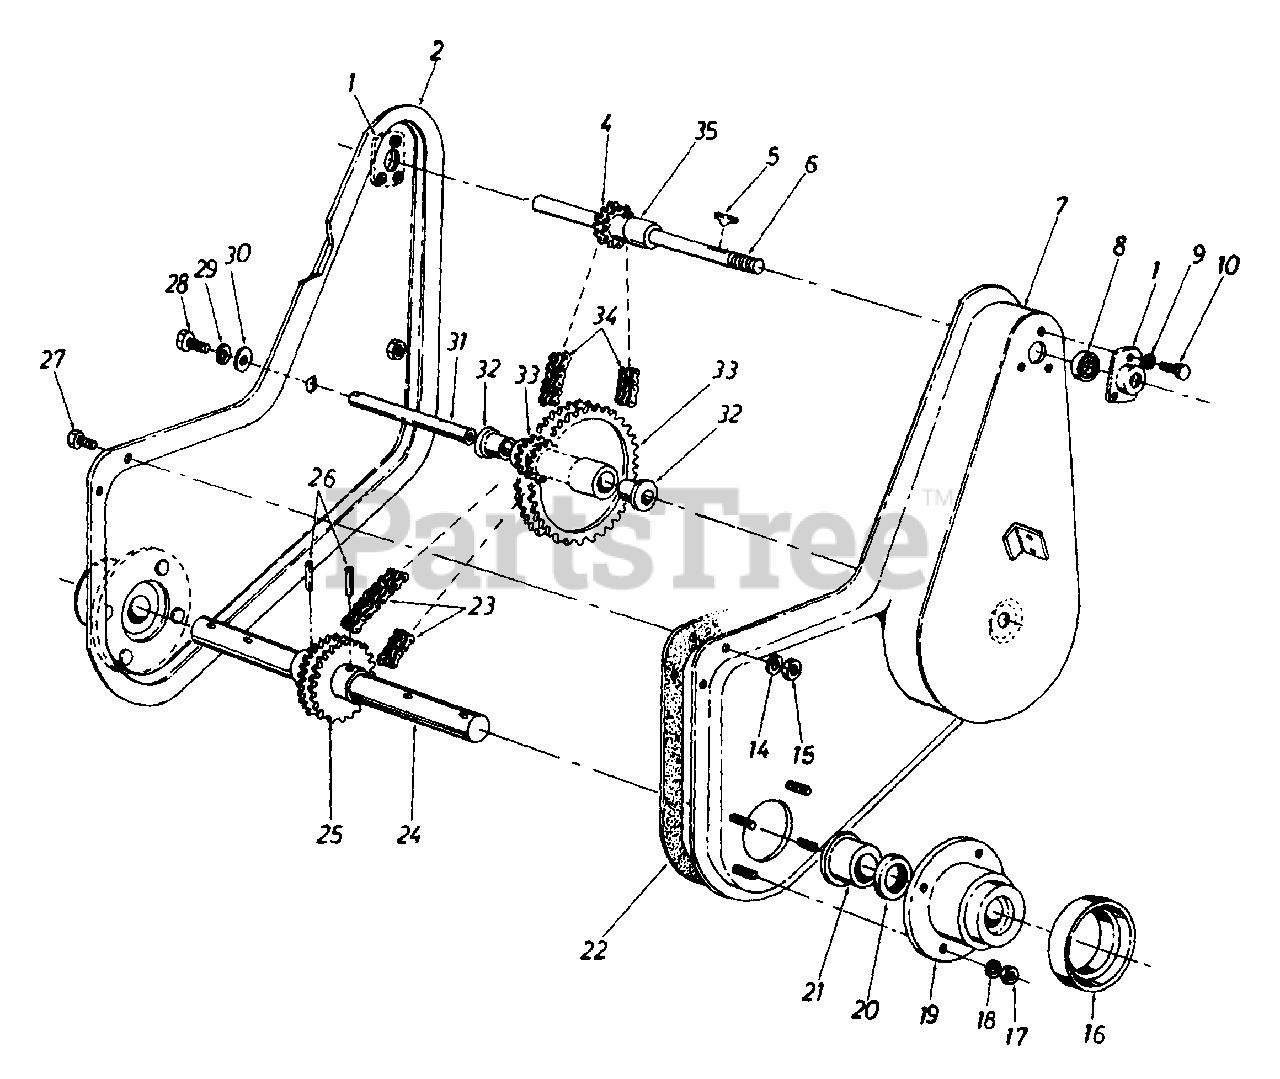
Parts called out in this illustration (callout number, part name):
1	Bearing Housing 1.375" Dia.
2	Housing Assembly - R.H.
5	#6 Hi-Pro Key 5/32" x .62" Lg.
6	Input Shaft Assembly
9	L-Wash. 1/4" I.D.
10	Hex Bolt 1/4-20 x .62" Lg.
14	L-Wash. 1/4" I.D.
15	Hex Cent. L-Nut 1/4-20 Thd.
16	Dust Cap Cover
17	Hex Cent. L-Nut 5/16-18 Thd.
18	L-Wash. 5/16" I.D.
19	Cast Bearing Housing
20	Oil Seal
21	Flange Bearing 1.25" 1.0. x 1.75" O.D.
22	Gasket
23	Roller Chain #40-2 x 34.0" Lg.
24	Tine Shaft
25	Double Sprocket T24-2 Teeth 1/2" Pitch
26	Spiral Pin 3/8" Dia. x 2.00" Lg.
27	Hex Bolt 1/4-20 x .62" Lg.
28	Hex Bolt 5/16-18 x .75" Lg.
29	L-Wash. 5/16" I.D.
30	Fl-Wash. 5/16" I.D.
31	Sprocket Shaft
32	Flange Bearing .62" I.D. x .75" O.D.
33	Double Sprocket Assembly
34	Roller Chain #35-2 x 36.75" Lg.
35	Spacer 5/8" I.D. x 7/8" O.D.
